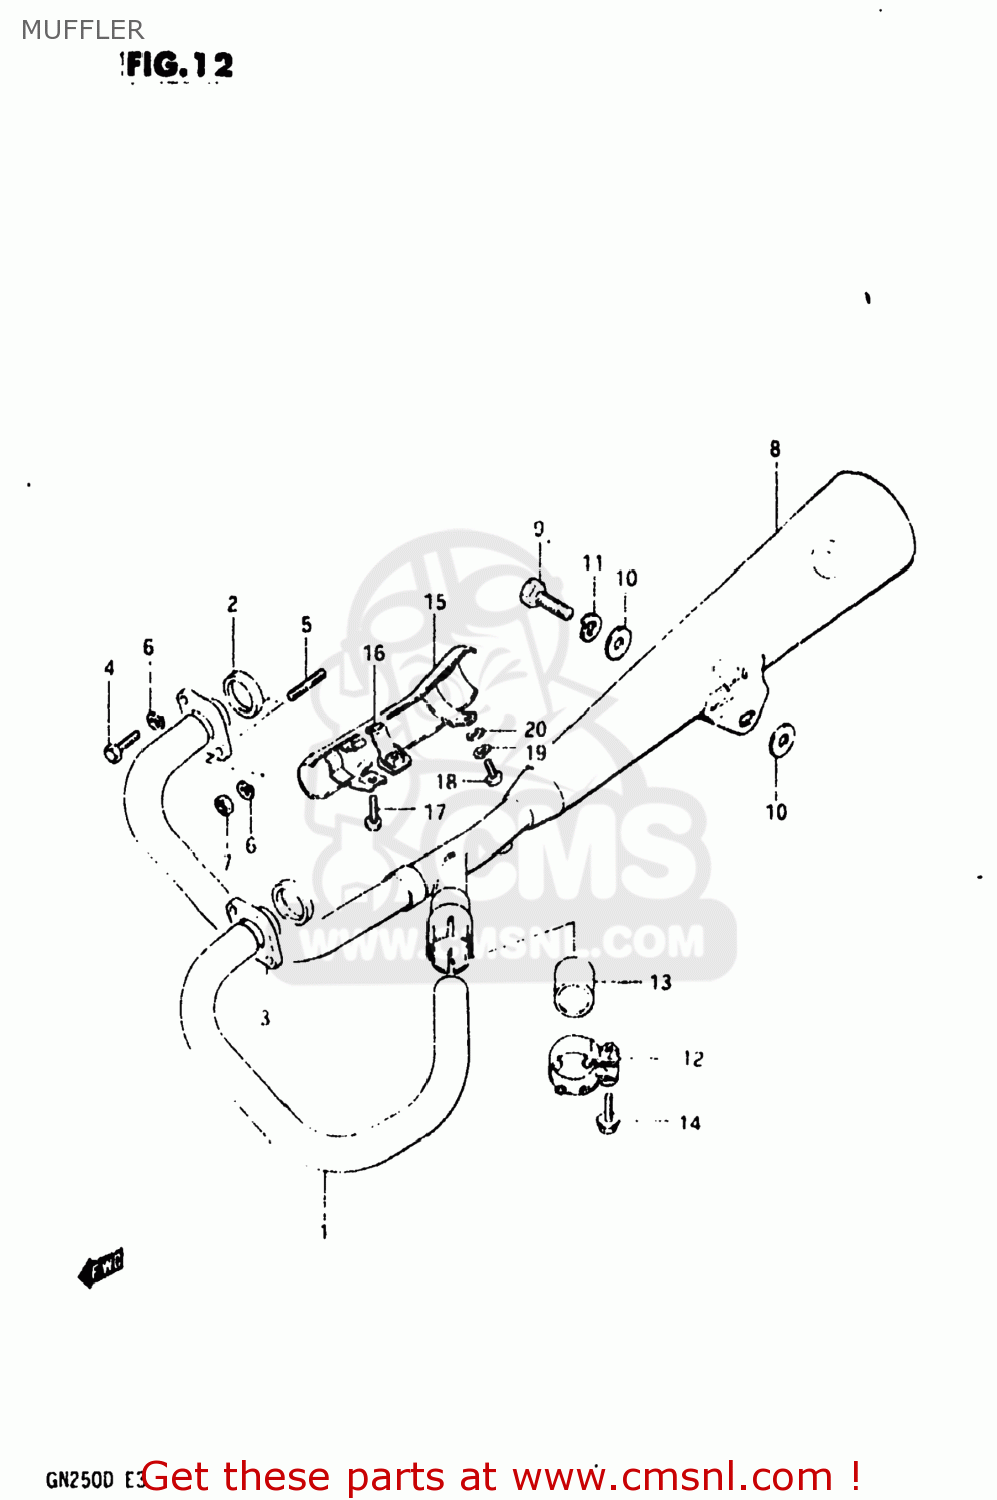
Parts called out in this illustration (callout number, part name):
1	PIPE,EXHAUST,L
2	GASKET,EXHAUST PIPE (NAS)
3	CLAMP
4	BOLT
5	STUD 6X20
6	LOCK WASHER
7	NUT
8	MUFFLER ASSEMBLY
9	BOLT 10X25
10	WASHER
11	LOCK WASHER
12	CLAMP
13	CONNECTOR,MUFFLER
14	BOLT
15	COVER,MUFFLER
16	CLAMP,MUFFLER COVER
17	SCREW
18	SCREW
19	LOCK WASHER
20	WASHER
